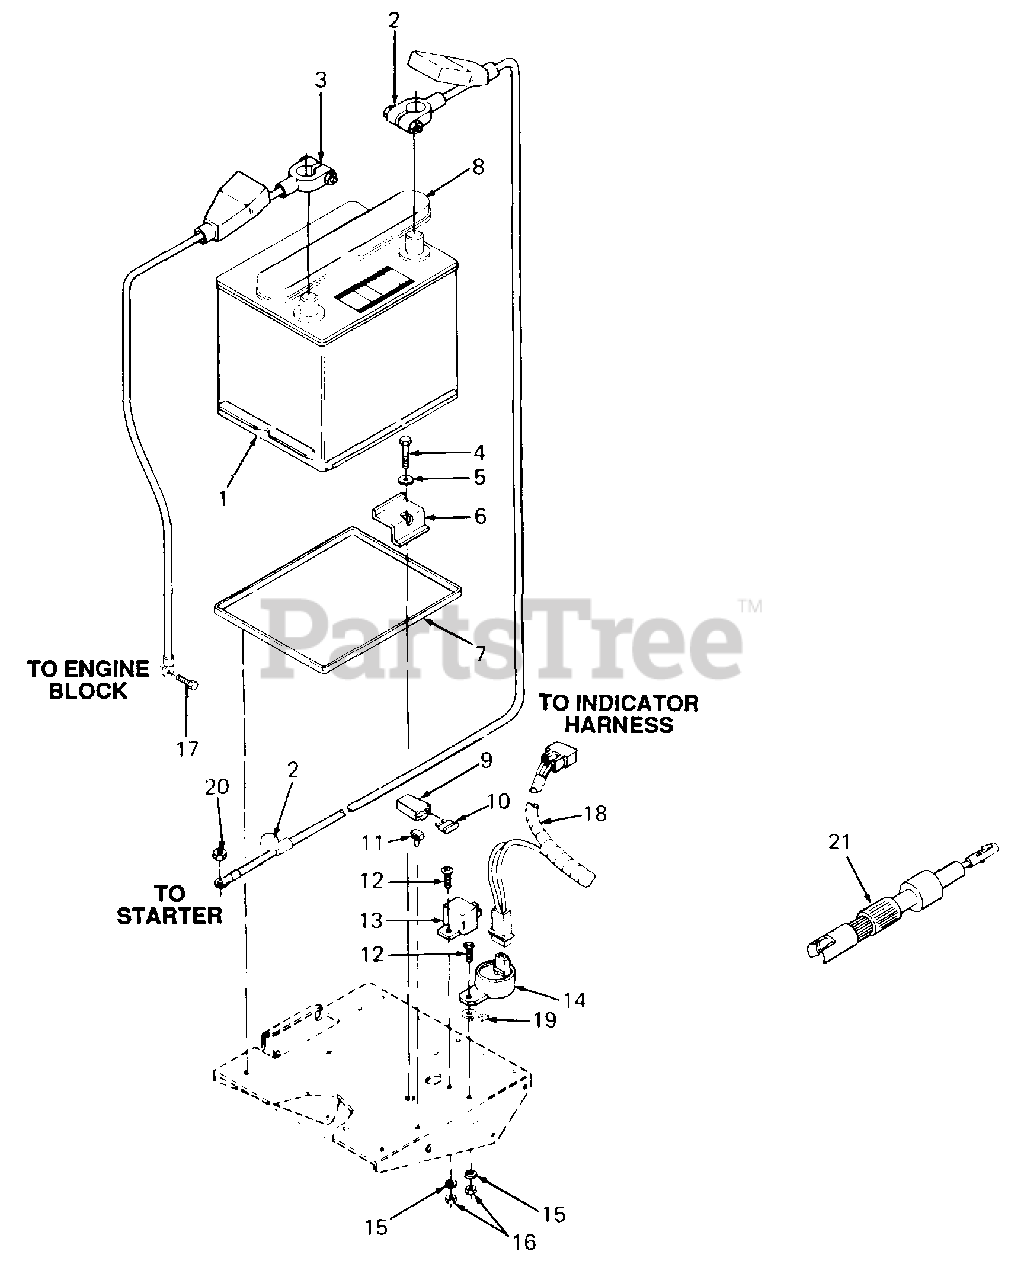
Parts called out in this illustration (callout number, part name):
1	Battery
2	Cable, Positive Battery
3	Cable, Negative Battery
4	Screw, Hex Cap, 5/16-18 x 1.38 Lg
5	Washer, Flat, .34 x .68 x .062 Thk
8	Cap, Battery Vent
9	Holder, Fuse
10	Fuse, 20 Amp
11	Clip, Fuse Holder Mtg
12	Screw, Truss Mach, #10-24 x .50 Lg
13	Relay
14	Indicator, Voltage
15	Washer, Lock, #10
16	Nut, Hex, #10-24
17	Screw, Hex Cap, M8-1.25 x 14 MM Lg
18	Main Harness
19	Lug, Quick Connect
20	Nut, Hex, M8-1.25 GR8.8
21	Diode Assy
